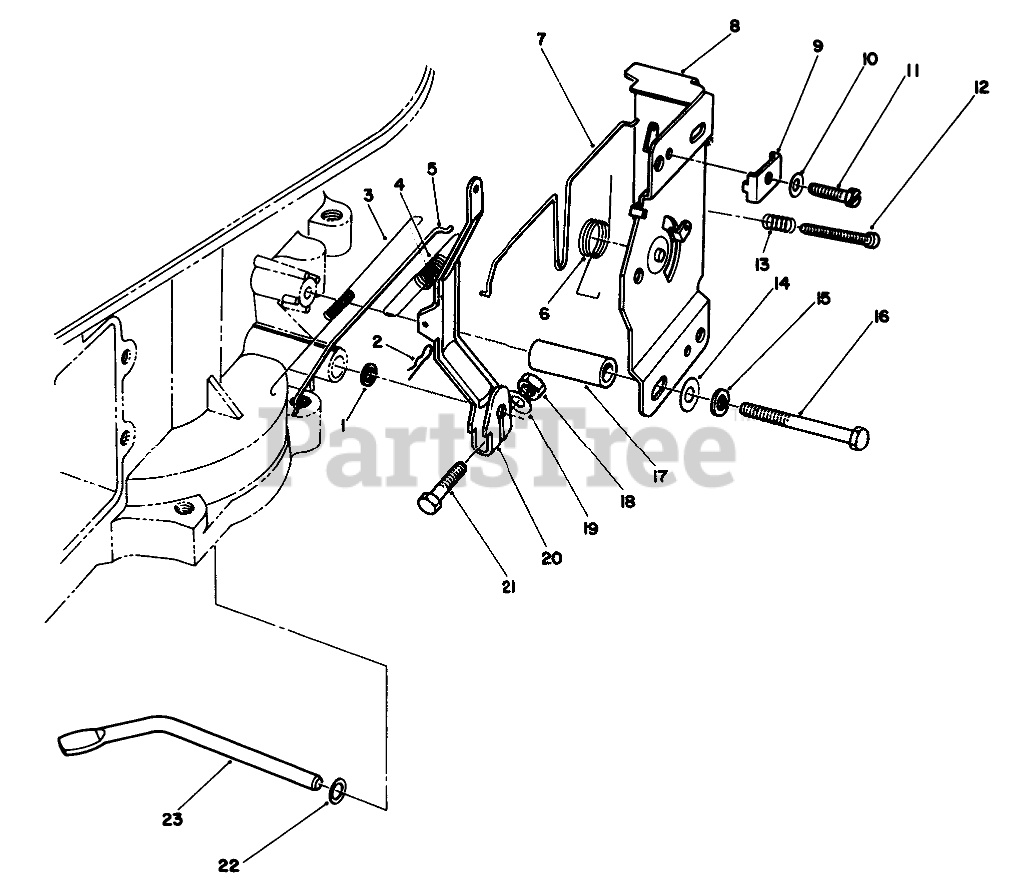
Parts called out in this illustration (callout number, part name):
1	SEAL-OIL (VC6X10X2.6)
2	Pin-Snap (1.2 X 21.2)
5	Link
7	LINK-Choke
8	Panel Incl #2 4-7
10	Washer
11	Bolt
15	Washer
18	NUT-HEX (6mm)
19	Washer-Plain (6mm)
20	Arm ASM
21	Bolt (6X28)
22	Washer
23	Arm-Pivot
